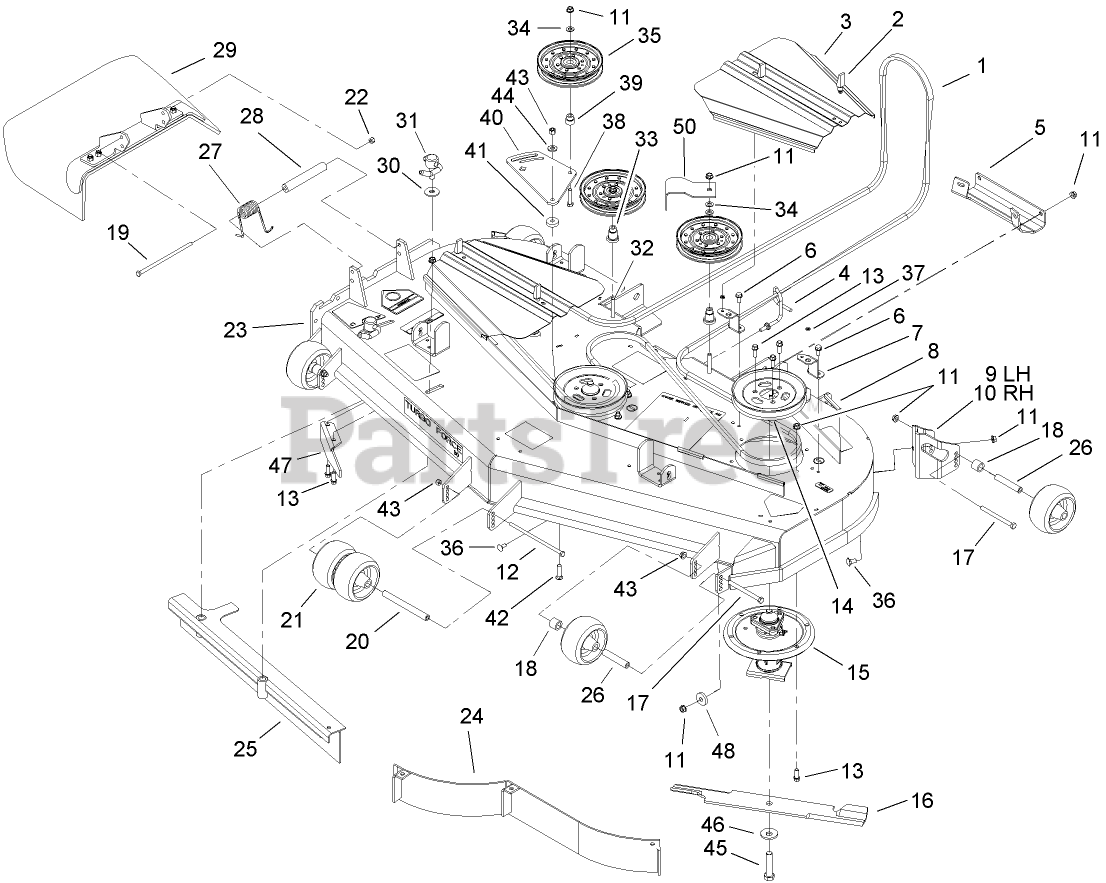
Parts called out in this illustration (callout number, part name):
2	LATCH-SWELL
3	Cover-Belt
4	GUIDE-BELT
5	Plate-Skid
6	SCREW-HWHTF
7	Bracket-Cover
8	STRIP-SEAL
9	MOUNT-WHEEL, LH
10	MOUNT-WHEEL, RH
11	NUT-HHF, WHIZ
12	SCREW-HH
13	SCREW-HWH
14	Pulley
15	Spindle ASM
16	BLADE-HI FLOW
17	SCREW-HH
18	TUBE-SPACER
19	SCREW-HH
20	SPACER-WHEEL
21	ROLLER-SCALP, ANTI
22	NUT-LOCK, NI
23	Deck Decal ASM
26	TUBE-SPANNER
27	SPRING-TORSION
28	SPACER
29	Rubber Deflector ASM
30	WASHER-PLASTIC
31	Lever ASM
32	SCREW-HH
33	MOUNT-PULLEY
34	WASHER-FLAT
35	Idler-Flat
36	SCREW-CARR
37	WASHER
38	SCREW-HH
39	BUSHING-IDLER
40	Plate-Idler
41	Spacer
42	SCREW-CARR
43	NUT-LOCK, NI
44	WASHER-BELLEVILLE
45	Screw-Cap
46	Washer-Blade Bolt, Heavy
47	BAFFLE-DISCHARGE
48	WASHER
50	GUIDE-BELT
